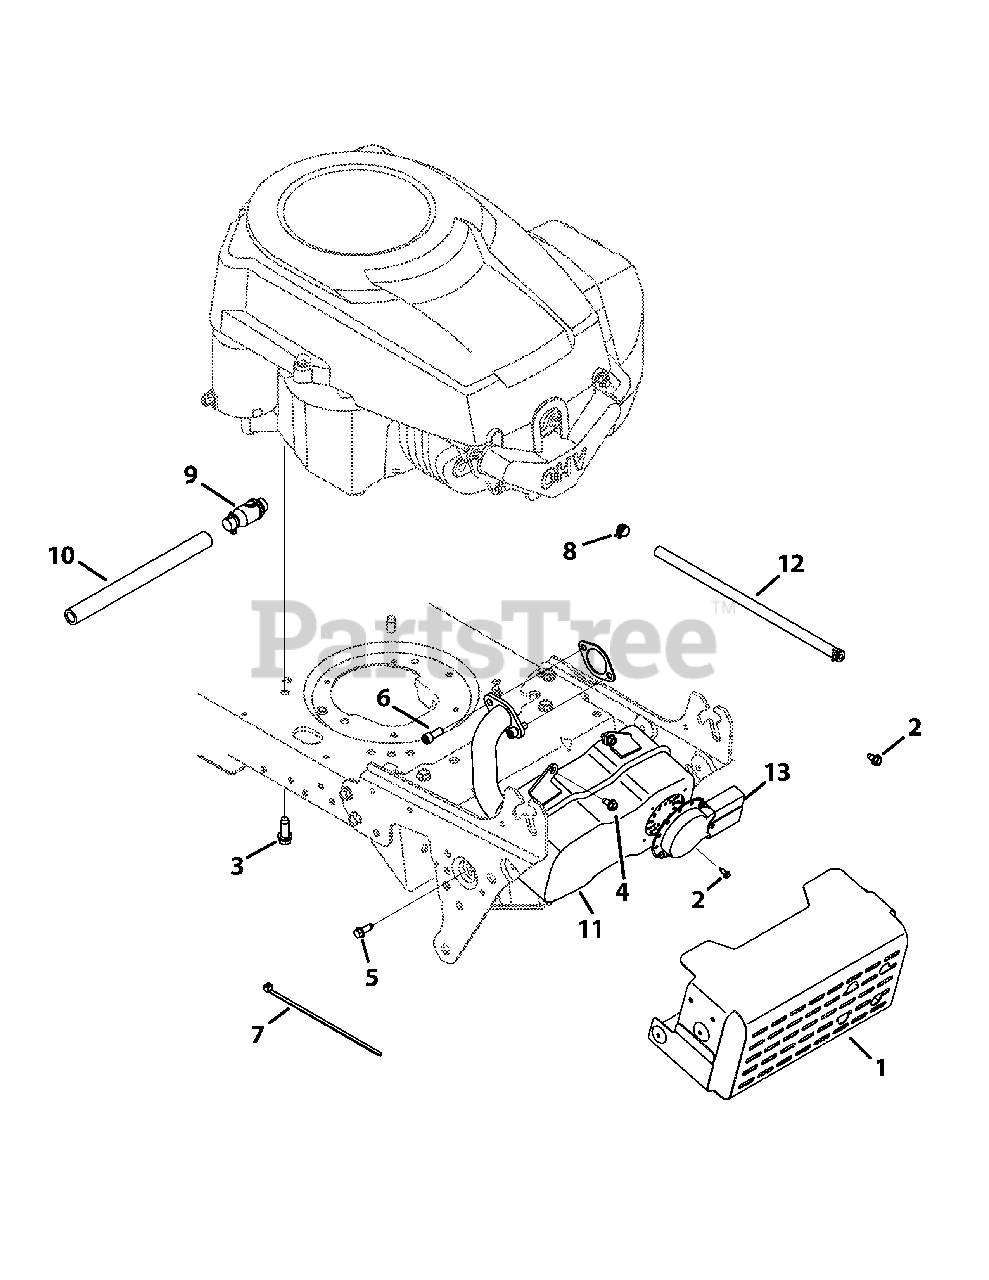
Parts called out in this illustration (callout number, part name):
1	Muffler Shield Assembly
2	Screw, 8-18 x .500
3	Screw, 3/8-16 x 1.0
4	Screw, 1/4-20 x .500
5	Screw, 1/4-20 x .750
6	Socket Screw, 5/16-18 x .750
7	Cable Tie
8	Clamp Hose, .490 diameter
10	Oil Drain, Extension Hose
11	Muffler
12	Fuel Hose, Low Permeation
13	Muffler Deflector Long
